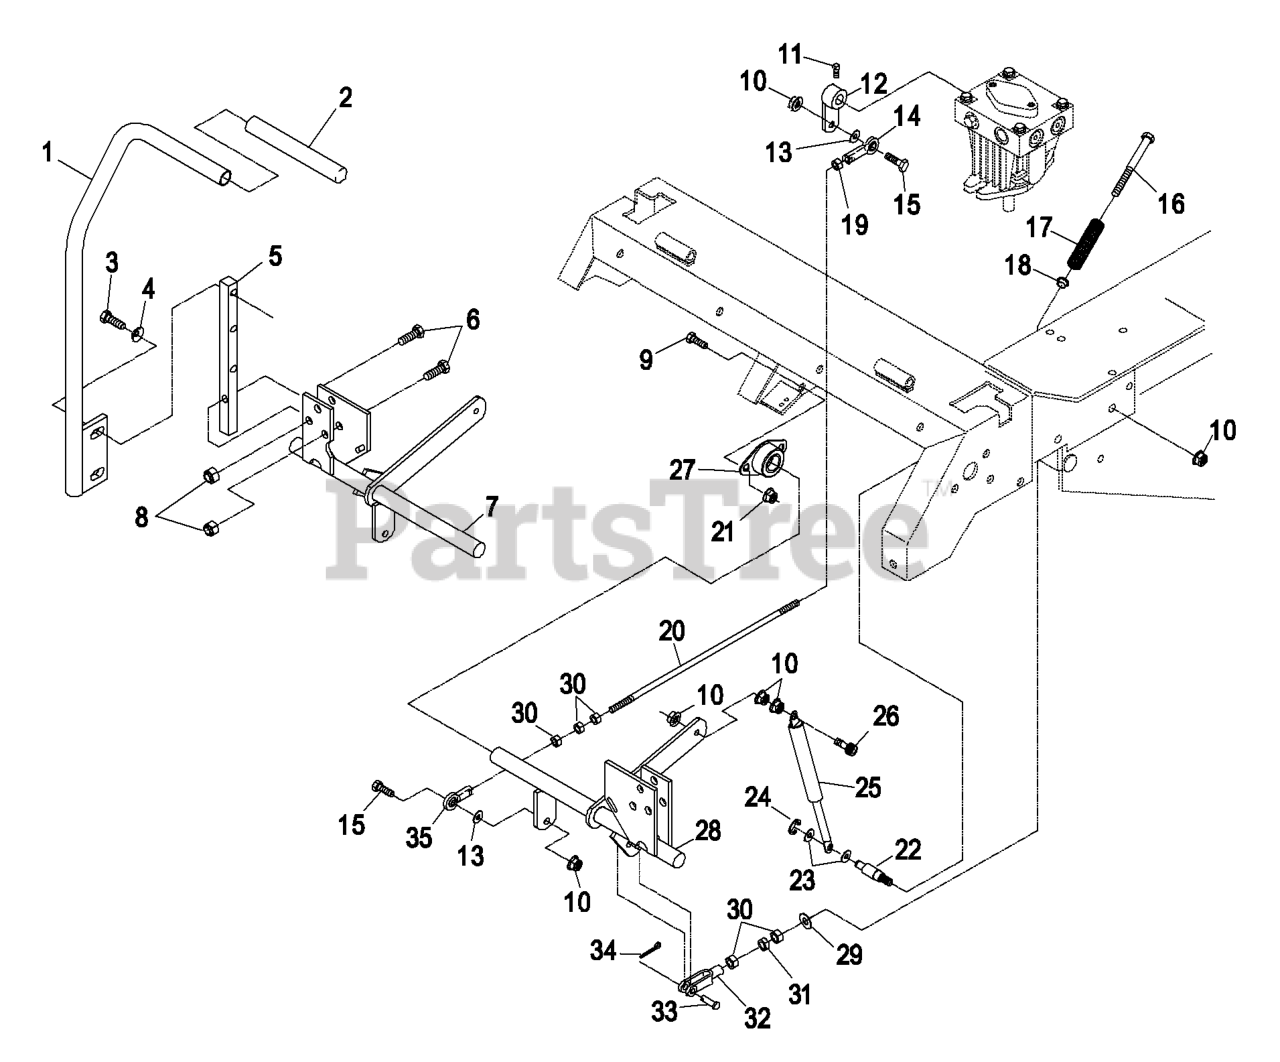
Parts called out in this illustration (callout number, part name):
1	RH LEVER ASM
2	GRIP-CONTROL, MOTION
3	SCREW-HH
4	WASHER-BELLEVILLE
5	ARM-SHAFT, CONTROL
6	SCREW-HH
8	NUT-LOCK, NI
9	SCREW-HH
11	SCREW-SET
13	WASHER-FLAT
14	BALLJOINT-LH
15	SCREW-HH
16	BOLT-RETURN, NEUTRAL
17	SPRING-RETURN, NEUTRAL
18	BUSHING-FLANGED
21	NUT-HHF, WHIZ
23	WASHER-PLAIN
24	RING-RETAINING, EXT
26	SCREW-HH
27	BEARING-FLANGE, SIDE
29	WASHER-FLAT
30	NUT-HEX
31	NUT-JAM
32	YOKE-ADJUSTABLE
33	PIN-CLEVIS
34	PIN-COTTER
35	BALLJOINT-RH
